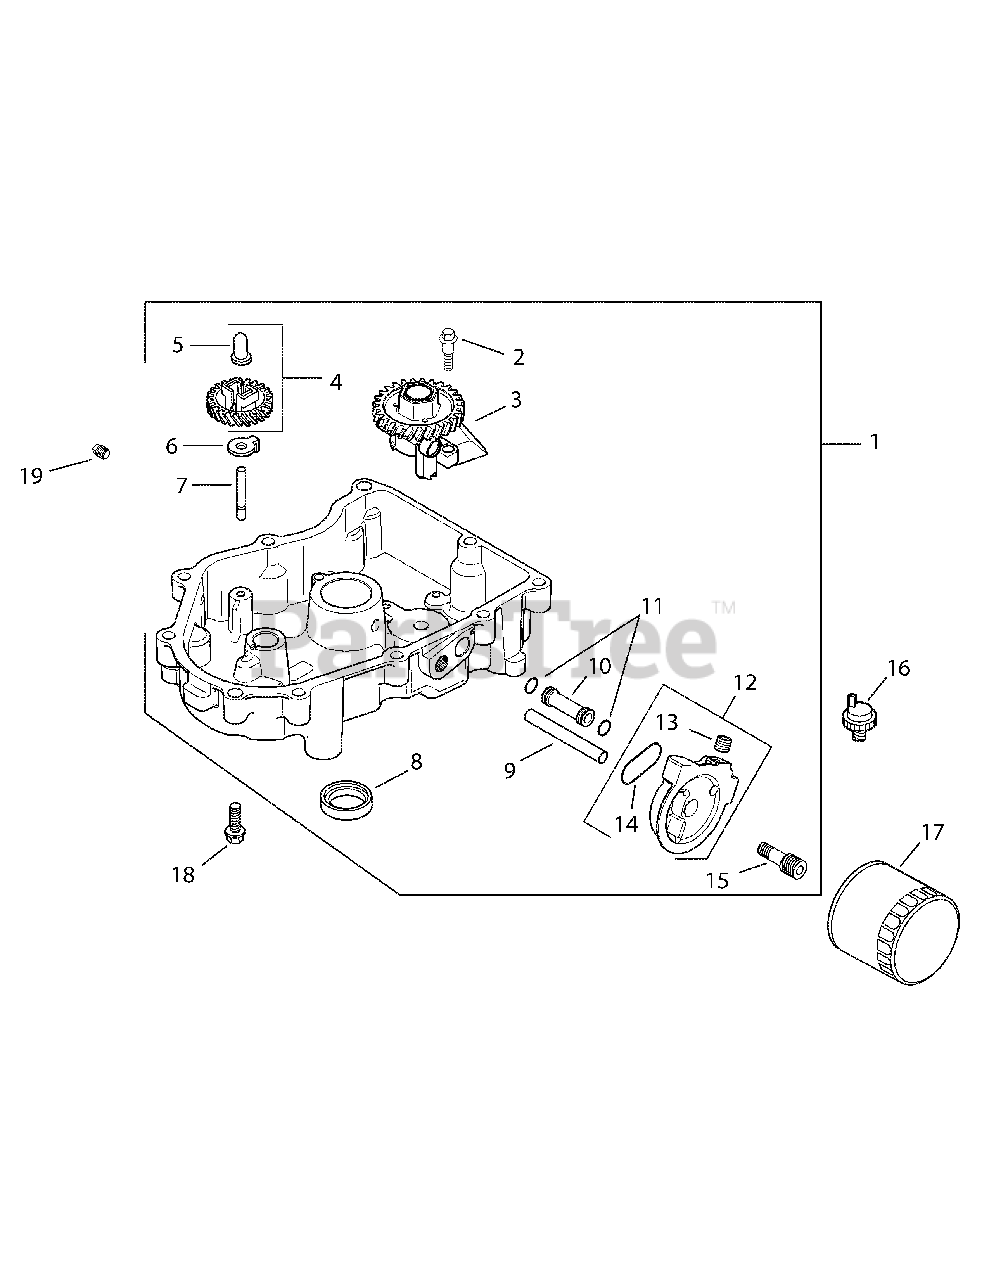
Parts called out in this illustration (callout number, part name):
1	Pan assembly, oil (Includes 2-15)
2	Screw, hex. flange thread forming shoulder
3	Oil pump assembly
4	Kit, governor gear w/pin (Includes 5)
5	Pin, governor regulating
7	Shaft, governor gear
8	Seal, oil (PTO end)
9	Tube, oil feed - filter to oil pan
10	Tube, oil feed - oil pan to filter
12	Kit, Adapter, oil filter
13	Plug, hex. ctsk. 1/8"
14	O-Ring, oil filter adapter
15	Nipple, oil filter
16	Switch, pressure
17	Filter, oil
18	Screw, hex. flange M8x1.25x45
19	Plug, sq. hd. solid 3/8"
